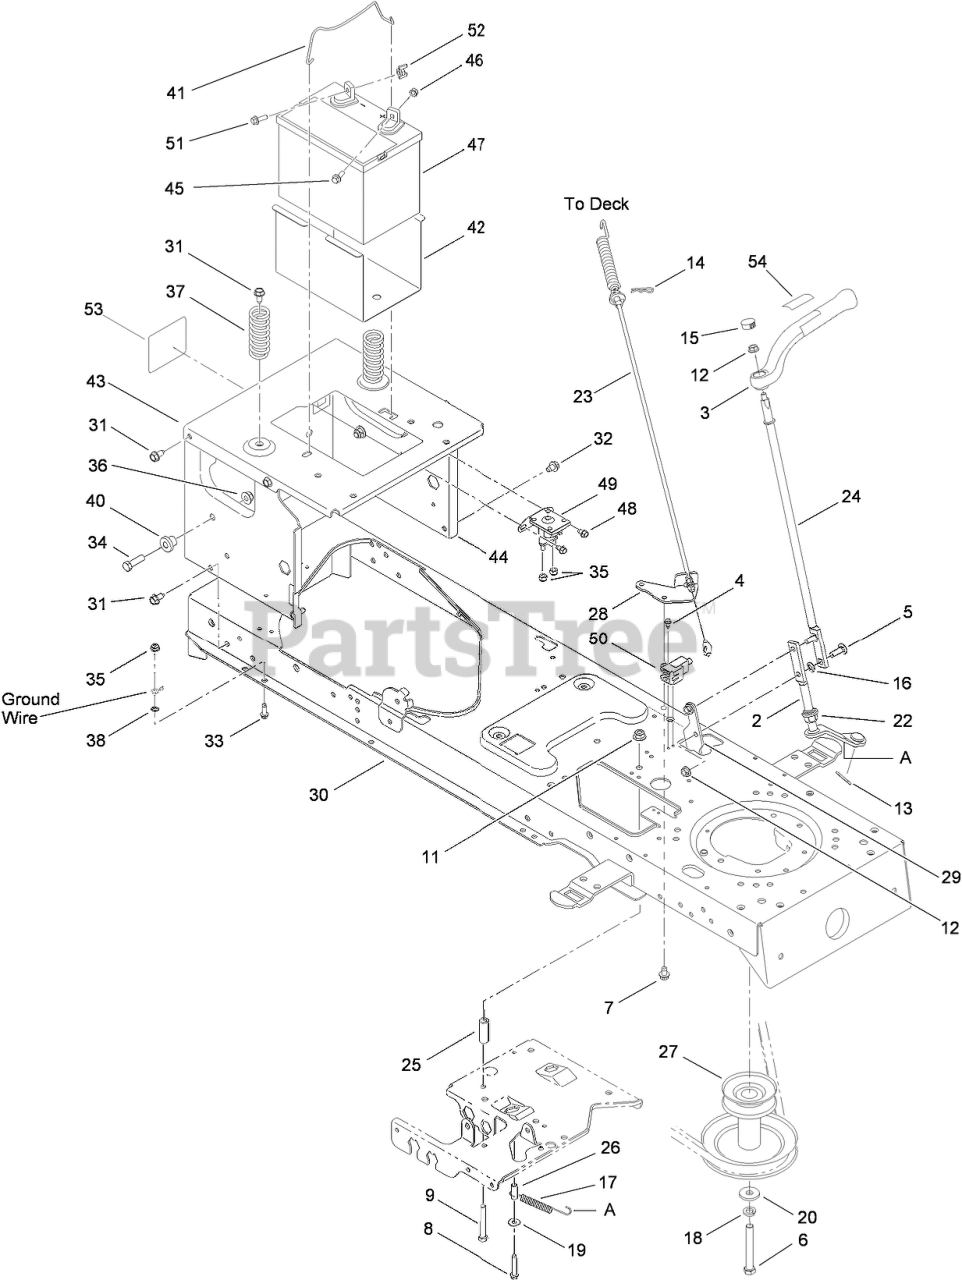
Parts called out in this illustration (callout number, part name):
2	LEVER-ENGAGE, PTO
3	KNOB PTO ASM
4	BOLT-SHOULDER
5	BOLT-CARR
6	SCREW-HH
7	SCREW-TAP
8	SCREW-HWH
9	SCREW-HH
11	NUT-LOCK, FLANGE
12	NUT-LOCK, FLANGE
13	PIN-COTTER
14	PIN-HAIR
15	PLUG-KNOB, PTO LEVER
16	NUT-PUSH
17	SPRING-EXTENSION
18	WASHER-LOCK
19	WASHER-FLAT
20	WASHER-FLAT
22	BEARING-FLANGE, HEX (SPLIT)
23	CABLE-ENGAGE, DECK
24	ROD-ENGAGE, DECK
25	SPACER
26	SPACER
27	PULLEY-ENGINE
28	BRACKET-MOUNT, CABLE
29	BRACKET-STOP
30	LOWER FRAME ASM
31	SCREW-TAP
32	SCREW-TAP
33	SCREW-TAP
34	SCREW-HH
35	NUT-LOCK, FLANGE
36	NUT-LOCK, FLANGE
37	SPRING-COMPRESSION
38	WASHER-LOCK, EXTERNAL
40	SPACER-SHOULDER
41	ROD-HOLDDOWN, BATTERY
42	TRAY-BATTERY
43	BRACKET-FRAME, SEAT
44	FRAME-UPPER
45	BOLT-CARRIAGE
46	NUT-SEMS
47	BATTERY-245, CCA (DRY FLAT TOP)
48	SCREW-TAP
49	SOLENOID-12V, 2 POST 2 Tab
50	SWITCH-INTERLOCK, NO/NC
51	BOLT-SHOULDER
52	NUT-WING, PLASTIC
53	DECAL-TORO
54	DECAL-PTO
